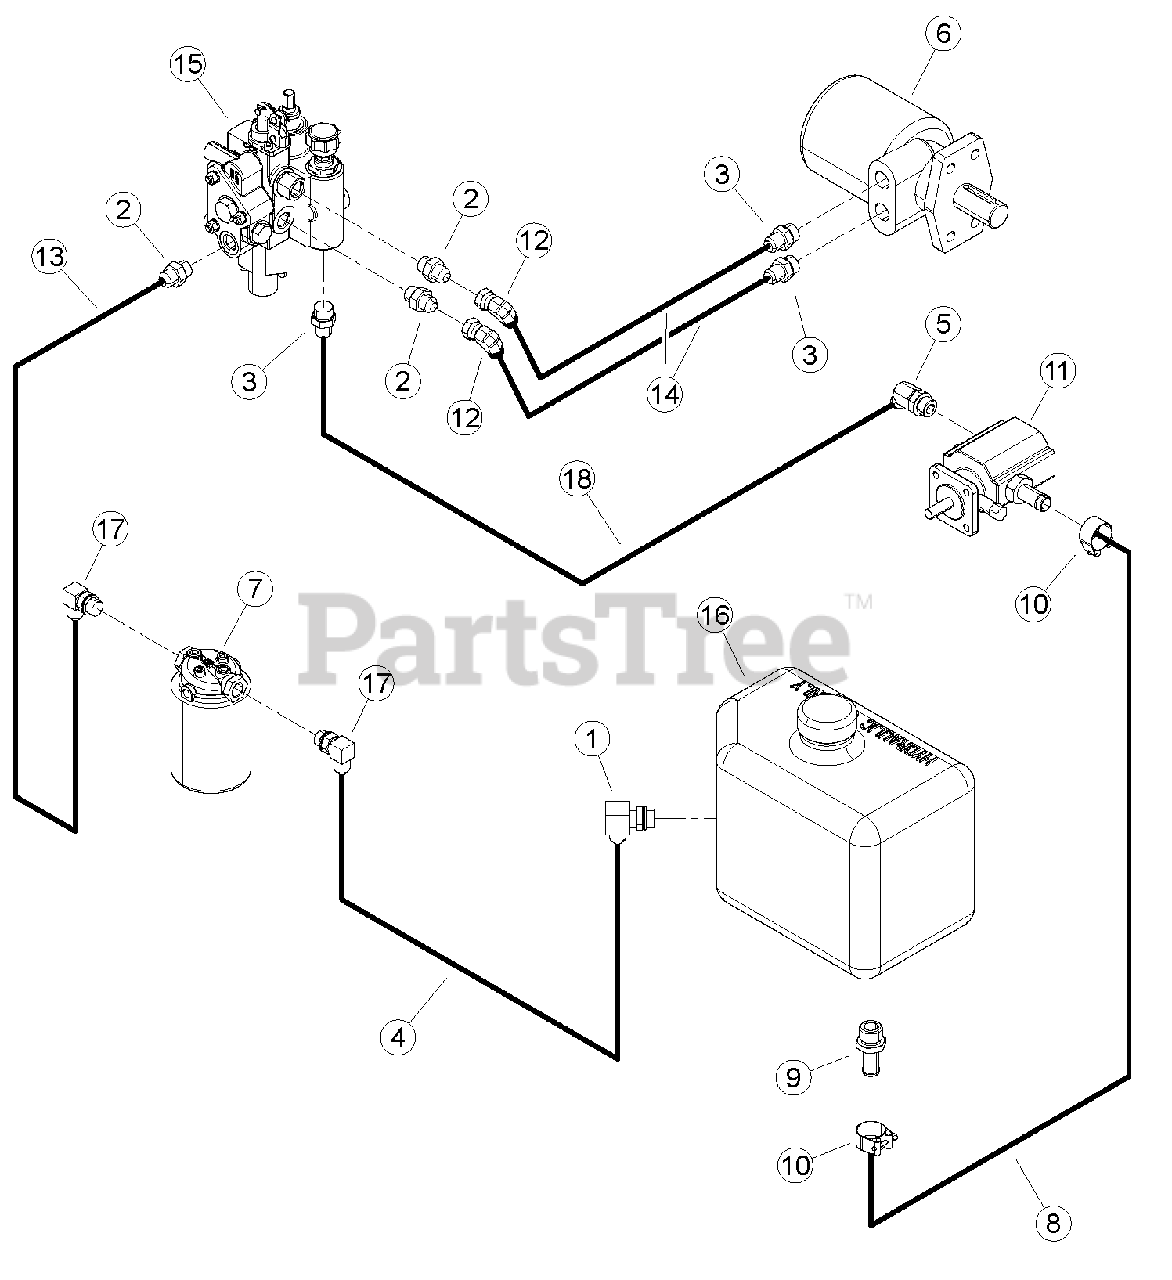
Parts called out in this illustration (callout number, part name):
1	ADAPTER, -10MORING/-8MJIC 90 DEG
2	ADAPTER, -8MORING/-8MJIC
3	ADAPTER, -10MORING/-8MJIC
4	HOSE ASSEMBLY, 8FMJIC/8FMJIC SW X 32"
5	ADAPTER, -10MORING/-8MJIC 45 DEG
6	MOTOR, 45 CU IN HYDRAULIC
7	ASSEMBLY, HYDRAULIC FILTER
8	HOSE, .75 ID X 21 IN 100R4 HYD
9	ADAPTER, -10 MORB/-12 HOSE BARB
10	CLAMP, 1-5/32 TO 7/32 OD RANGE T-BOLT
11	PUMP, 2 STAGE CW HI/LO 0.605 DISP.
12	ADAPTER, SWIVEL -8MJIC / -8FMJIC
13	HOSE, .500" X 112" -8FMJICSW/-FMJICSW 90
14	HOSE, .375" X 35" -8FMJICSW/-8FMJICSW 90 MED DROP
15	VALVE, 4-WAY 4-POSITION FC & RELIEF
16	TANK, HYDRAULIC
17	ADAPTER, -8MORING/-8MJIC 90 DEG
18	HOSE, 3/8 X 35 -8FJICSW
